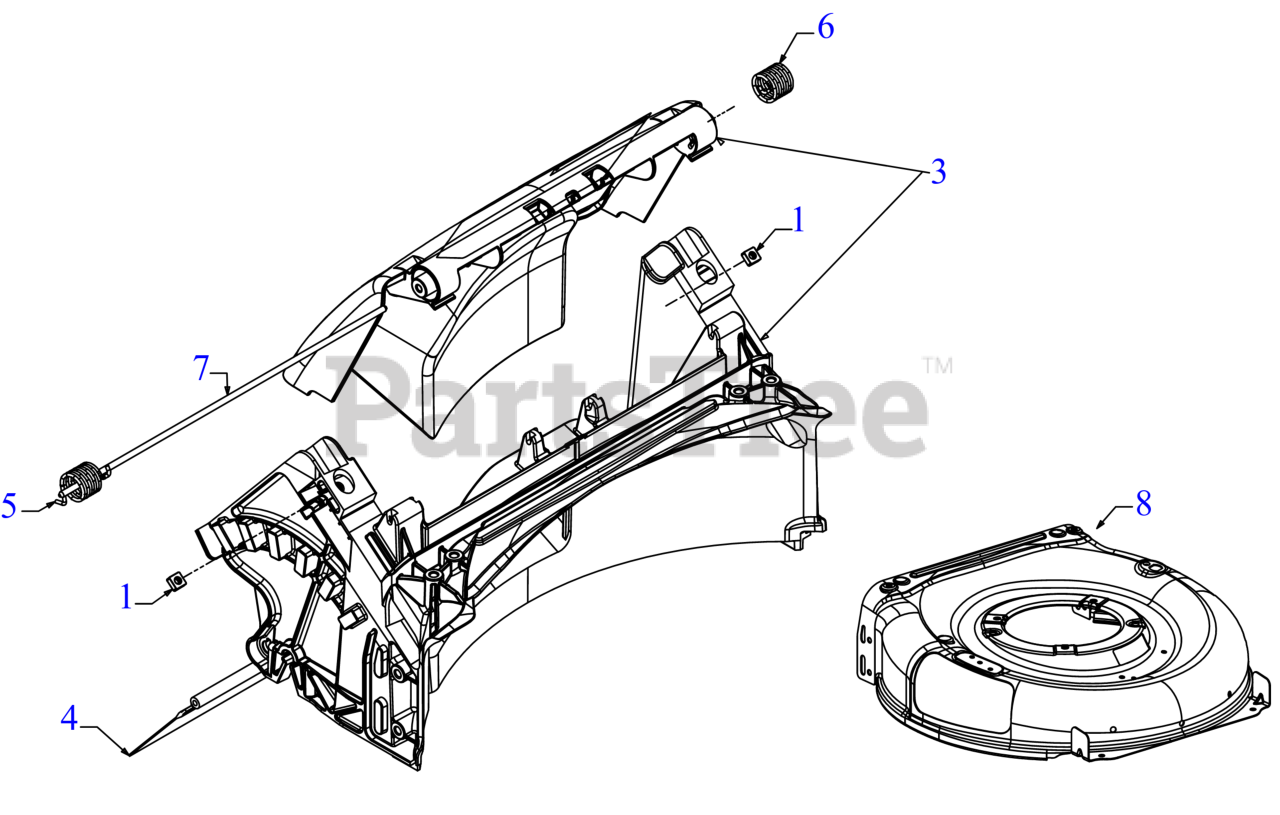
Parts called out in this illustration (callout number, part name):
1	SQUARE NUT 1/4-20
3	REAR BAG DOOR ASSEMBLY
4	TRAILSHIELD
5	TORSION SPRING (RH)
6	TORSION SPRING (LH)
7	REAR DOOR PIVOT ROD
